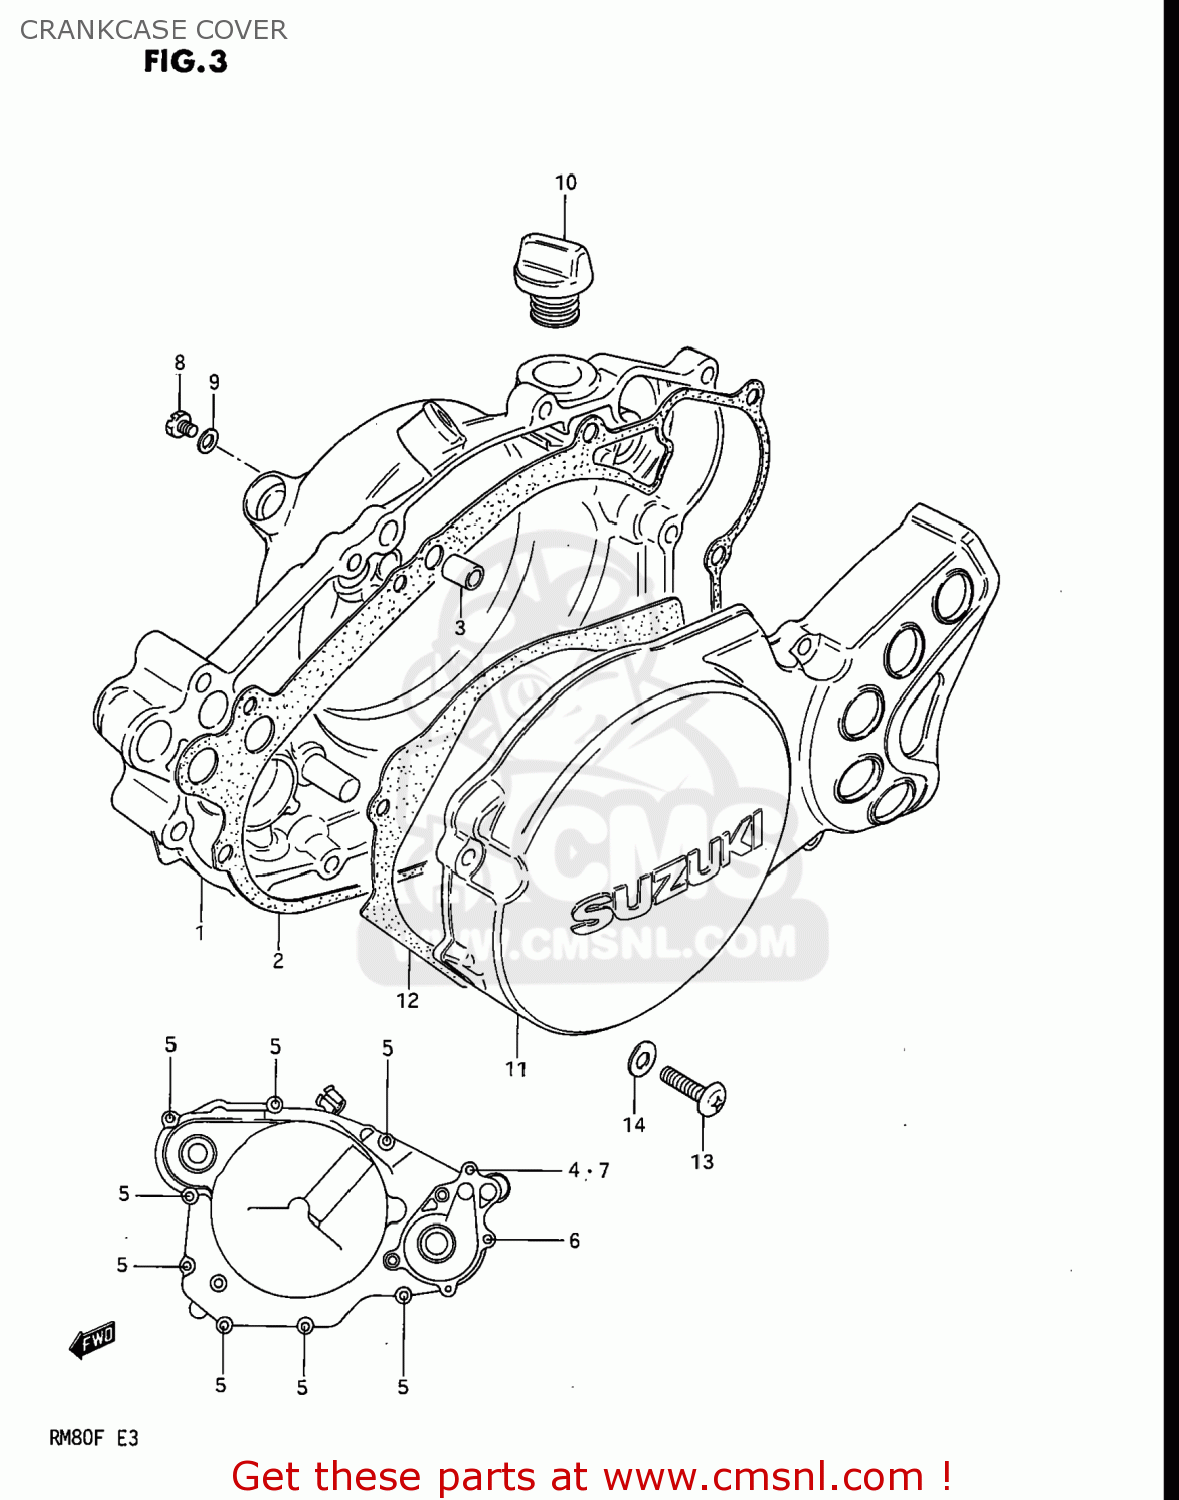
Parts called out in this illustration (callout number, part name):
1	COVER,CLUTCH
2	GASKET,CLUTCH COVER (MCA)
3	PIN
4	GASKET (NAS)
5	SCREW
6	SCREW
7	SCREW
8	SCREW(6X10)
9	GASKET(6.2X11X1) (NAS)
10	PLUG
11	COVER
12	GASKET,MAGNETO COVER (NAS)
13	SCREW 5X20
14	WASHER,5MM
